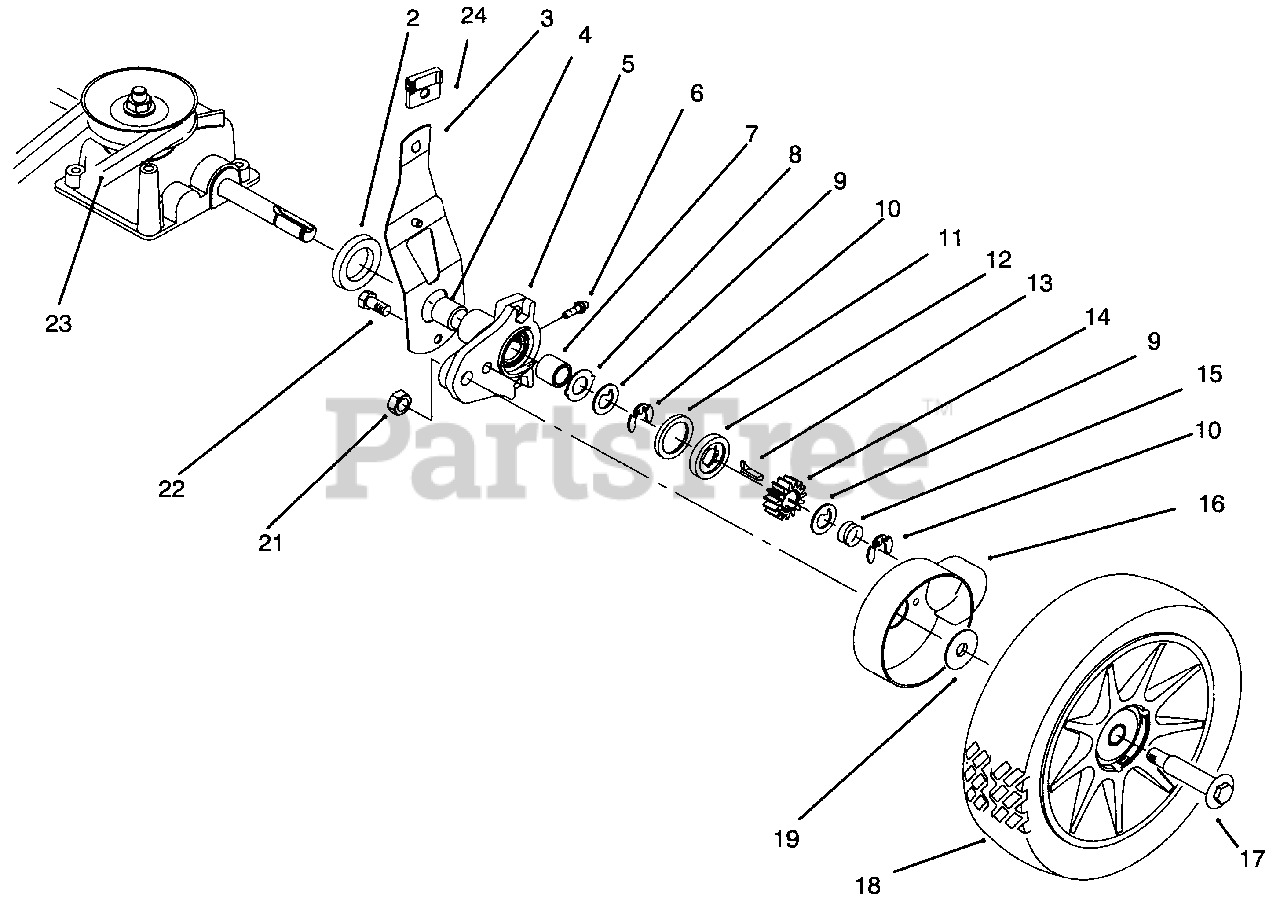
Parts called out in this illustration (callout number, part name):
2	Spacer-Axle Shaft
3	Spring Arm Ass'y
5	Pivot Arm Ass'y-Rear (Incl. Ref.#4, 6, & 8)
6	Fitting-Grease
8	Washer-Thrust Pivot Arm
9	Washer-Thrust, Keyed
10	Ring-Klip. Special
11	Ring-Friction
12	Washer-Clutch, Plastic
13	Key-Rocking, LH
14	Gear-Pinion
15	Spring-Compression
16	Cover Wheel
17	Bolt-Wheel
18	Wheel Ass'y-8"
19	Washer-Stepped
